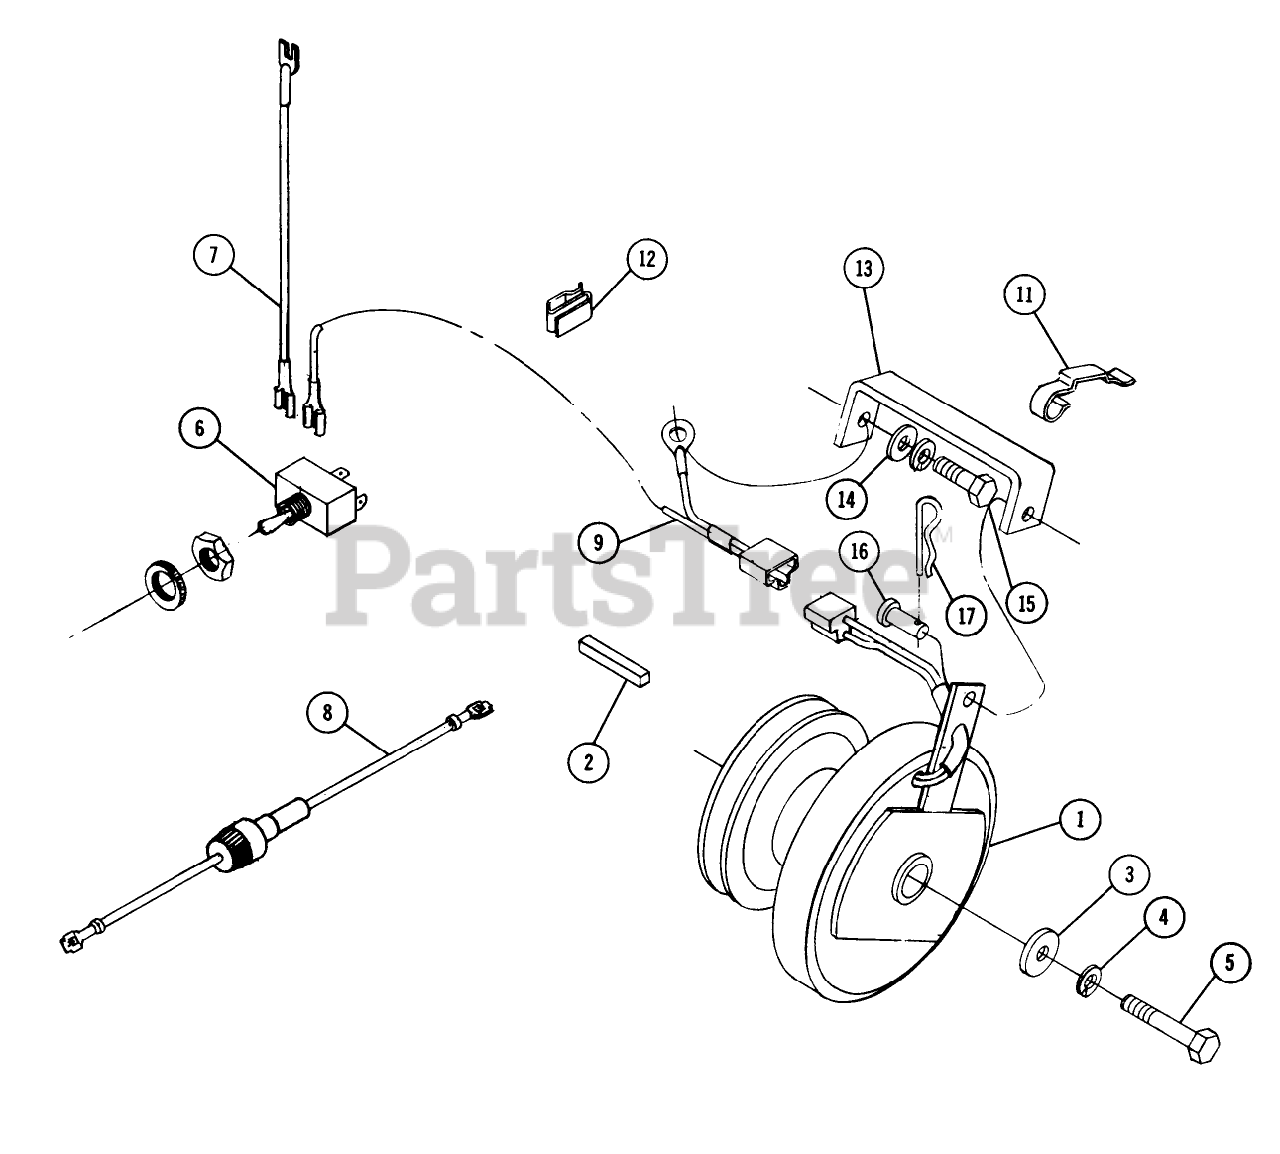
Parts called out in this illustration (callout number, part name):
1	ELECTRIC CLUTCH
2	Key
3	Washer
4	Lockwasher 3/8
5	Bolt Hex 7/16-20 x 2
6	SWITCH CLUTCH
7	Wire
8	ASSY FUSED CONNECTOR
9	Wire-Clutch
11	Clip
12	SPEED CLIP
13	Bracket Assembly
14	Washer
15	Bolt, 7/16 14 x 1
17	Hairpin
